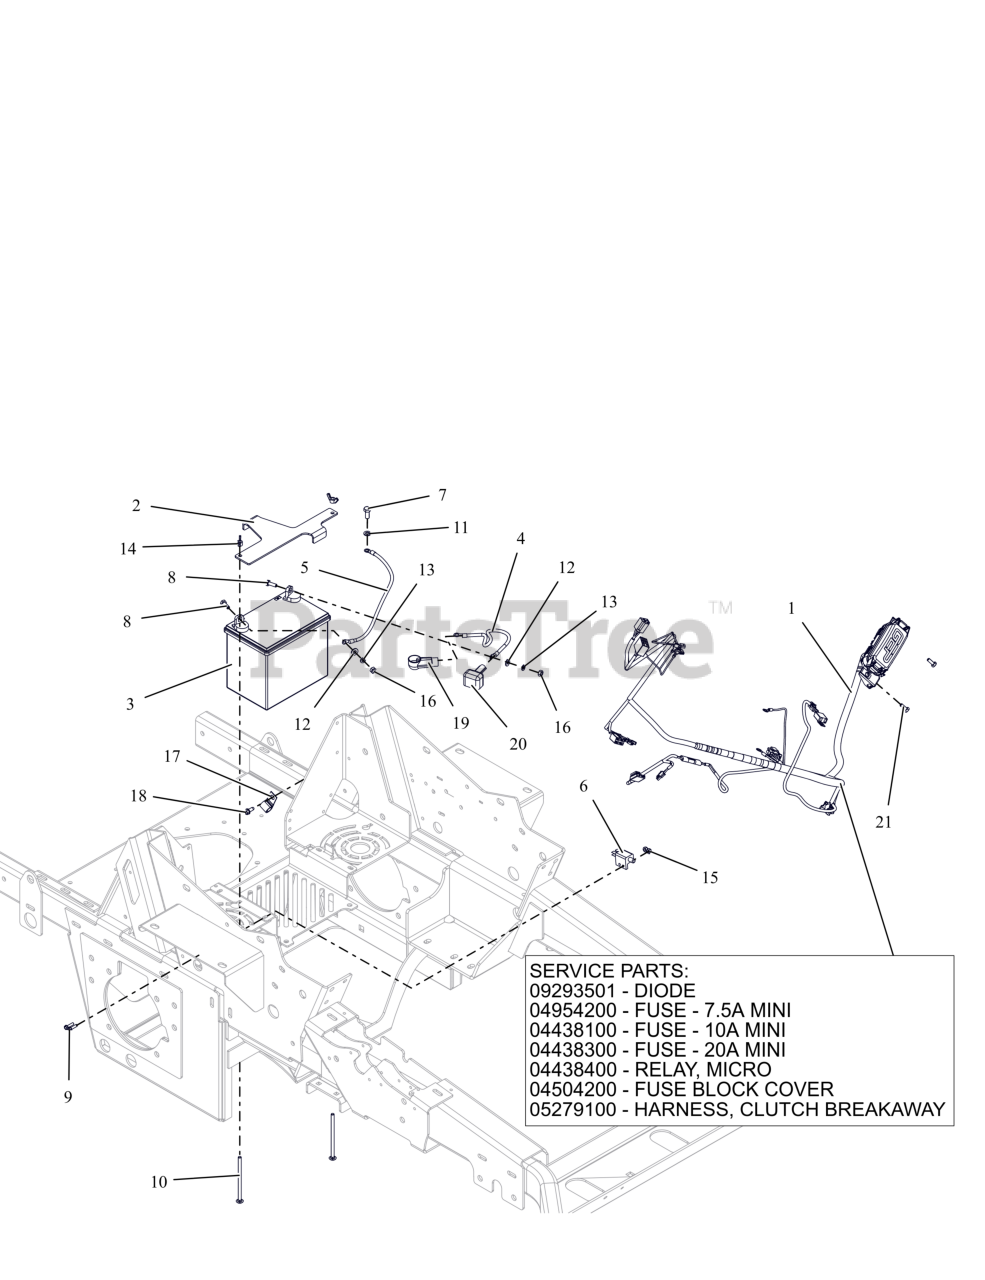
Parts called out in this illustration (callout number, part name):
1	HARNESS- WIRE PT300 MAIN
1	DIODE, CONNECTOR SHELL
1	FUSE, 7.5 AMP MINI-ATC
1	FUSE,10 AMP MINI-ATC
1	FUSE,20 AMP MINI ATC
1	RELAY,MICRO5 TERML W/RESISTOR
1	COVER, HARNESS FUSE/RELAY MOD
1	HARNESS, CLUTCH BREAKAWAY
2	HOLDDOWN- BATTERY
3	BATTERY, 300 CCA 10U1L
4	CABLE, STARTER 13.00"
5	CABLE-GROUND .25 X 13.00 X .31
6	SWITCH- DOUBLE POLE N.O./N.O.
7	BLT, HEX M8-1.25X20 G8.8 ZCC
8	BLT, HEX .25-20X.75 G5 ZCC
9	BLT, HWH #10-24X.75 ZCC
10	BLT, RHSN .25-20X4.50 G5 ZCC
11	WSHR,LK-REG .312X.078 ZCC
12	WSHR,FLT .281X.625X.065 ZCC
13	WSHR,LK-REG .250X.062 ZCC
14	NUT, LK-WING .25-20 ZCC
15	NUT-LK-NYL #10-24 G2 ZCC
16	NUT-STD .250-20 G2 ZCC
18	SCR,TAP .25-20X.625 HWH ZCC
19	BOOT, .65ID POS
20	INSULATOR
21	BLT, HEX M6-1X16 G8.8 ZCC
